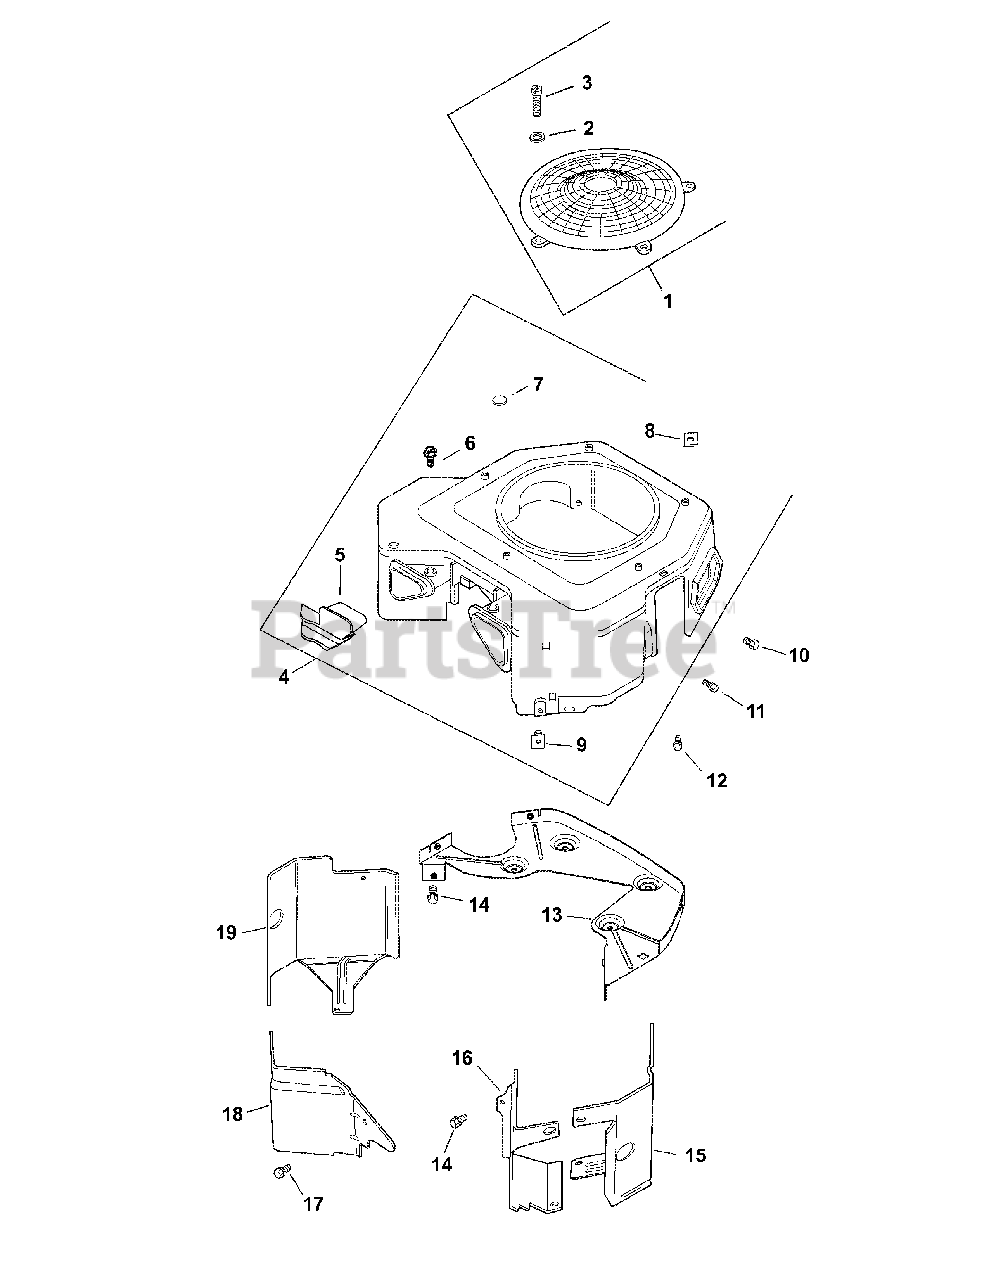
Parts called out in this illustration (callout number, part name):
1	Kit, Blower Housing Assembly
3	Cover, Blower Housing
4	Screw, Wsh Hd Tap #8-18 x 1/2"
5	Plug, Button 9/16
7	Kit, Fixed Guard
9	Screw, FLG THD FRM M5 x .8 x 16
10	Screw, FLG THD FRM M5 x .8 x 16
11	Screw, FLG THD FRM M5 x .8 x 20
12	Kit, Backing Plate
13	Screw, FLG THD FRM M6 x 1.0 x 16
14	Baffle, Cyl Barrel #2 Side
15	Baffle, Valley-#2 Side
16	Screw, FLG THD FRM M5 x .8 x 10
17	Baffle, Valley #1 Side
18	Baffle, Cyl Barrel - #1 Side
